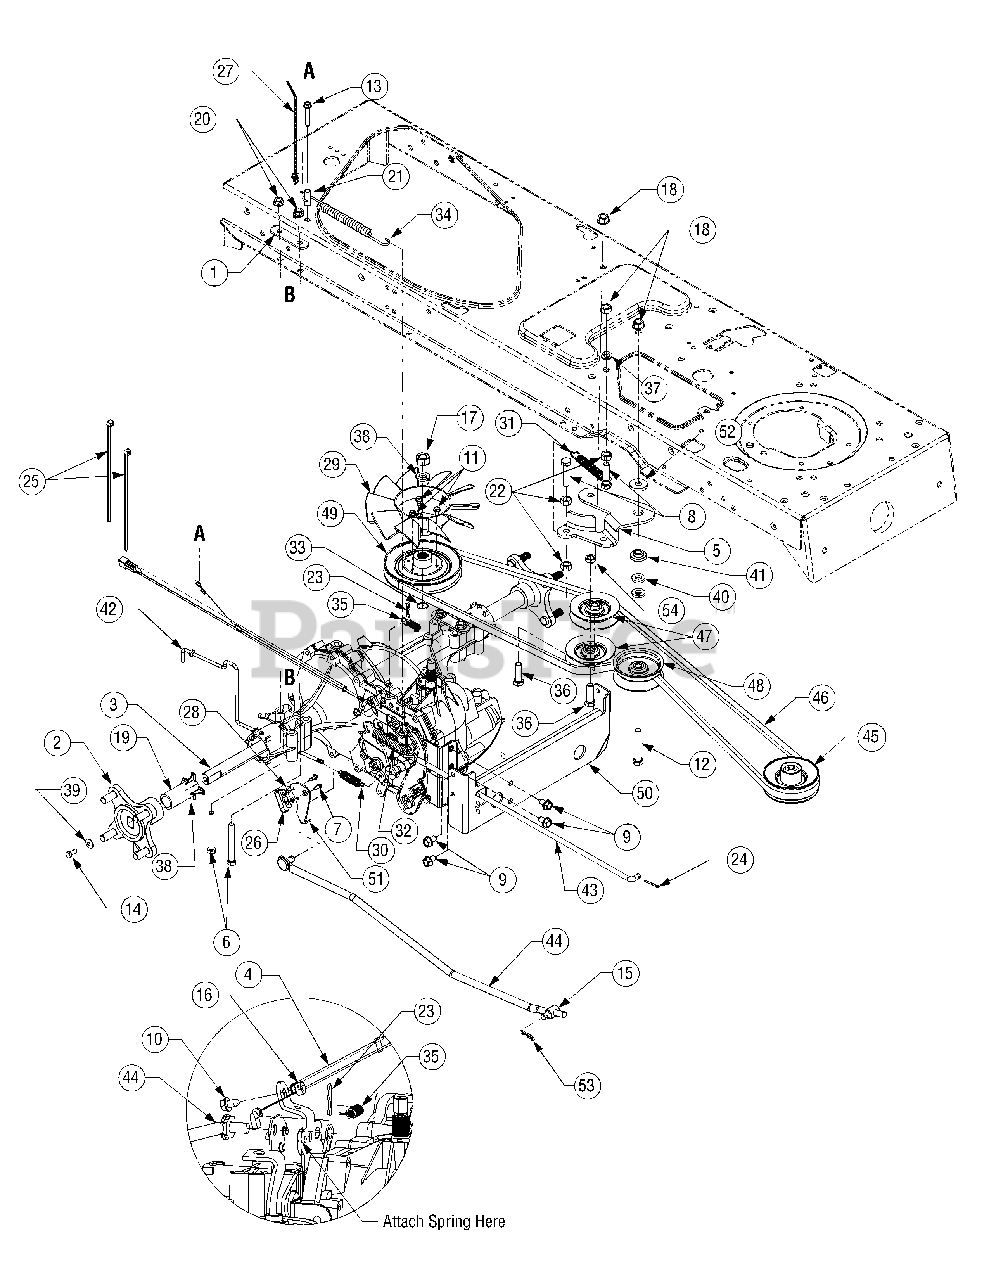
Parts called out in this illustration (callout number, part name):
2	Hub Assembly, Wheel
3	Transmission, Hydrostatic
3	Transmission, Hydrostatic w/ Drain
4	Harness Assembly, Ground & Reverse
6	Hex Cap Screw, 5/16-18,3.5, Gr5
7	Screw, #8-18, 0.500
8	Hex Cap Screw, 3/8-16, 1.50, Gr5
9	Screw, 5/16-12, 0.75
10	Screw, 1/4-20, 0.5
11	Screw, #12-24, 0.375
12	Hex Cap Screw, 3/8-16, 2.25, Gr5
13	Hex Cap Screw, 1/4-20, 1.5, Gr5
14	Hex Cap Screw, 5/16-24 x .750
15	Ferrule, 3/8-24 x .375 Dia
16	Nut, Hex Nylon Lock, 1/4-20
17	Nut, Hex, 1/2-20, Gr5
18	Nut, Nylon Lock, 3/8-16
19	Sleeve, 2.4"
20	Nut, Nylon Lock, 5/16-18, Gr5
21	Spacer, 1"
22	Nut, Hex, 3/8-16, Gr8
23	Pin, Cotter, .072 Dia. x 1.13 Lg
24	Pin, Cotter, 3/32, 1.0
25	Cable, Tie, 3/16 x .05 x 7.4
26	Switch, Spring, Short
27	Tie, Cable, Push Mount 7.5 Lg
28	Plate, Insulator Nut
29	Fan, Blade, 10"
30	Spring, .48 OD x 2.03 Extension
31	Spring, Extension, .563 Dia x 3.72 Lg
32	Spring, Extension, .59 OD x 4.00 Lg
33	Ring, Wire
34	Spring, Extension, .500 Dia x 7.0
35	Spring, Extension, 3/8 OD x 1.44
36	Screw, 3/8-16, 1.25
37	Washer, Lock, 3/8, Regular Duty
38	Washer, Lock, 1/2
39	Bell Washer
40	Washer, Flat, .407 x .812 x .135
41	Spacer, Shoulder, 1.00 x .38 x .38
42	Rod, Hydro Bypass
43	Rod, Brake, Hydro
44	Rod, Control, Hydro
45	Pulley, Engine
46	Belt, V Type, Poly, 78"
47	Pulley, Idler, V Type x 3.06 Dia
48	Pulley, Idler, Flat 2.75 OD
49	Pulley, Engine, 4.11Dia.
52	Washer, Flat, .38 x 1.92 x .060
53	Pin, Cotter, 3/32, .750
54	Spacer, .38 x .625 x .21
